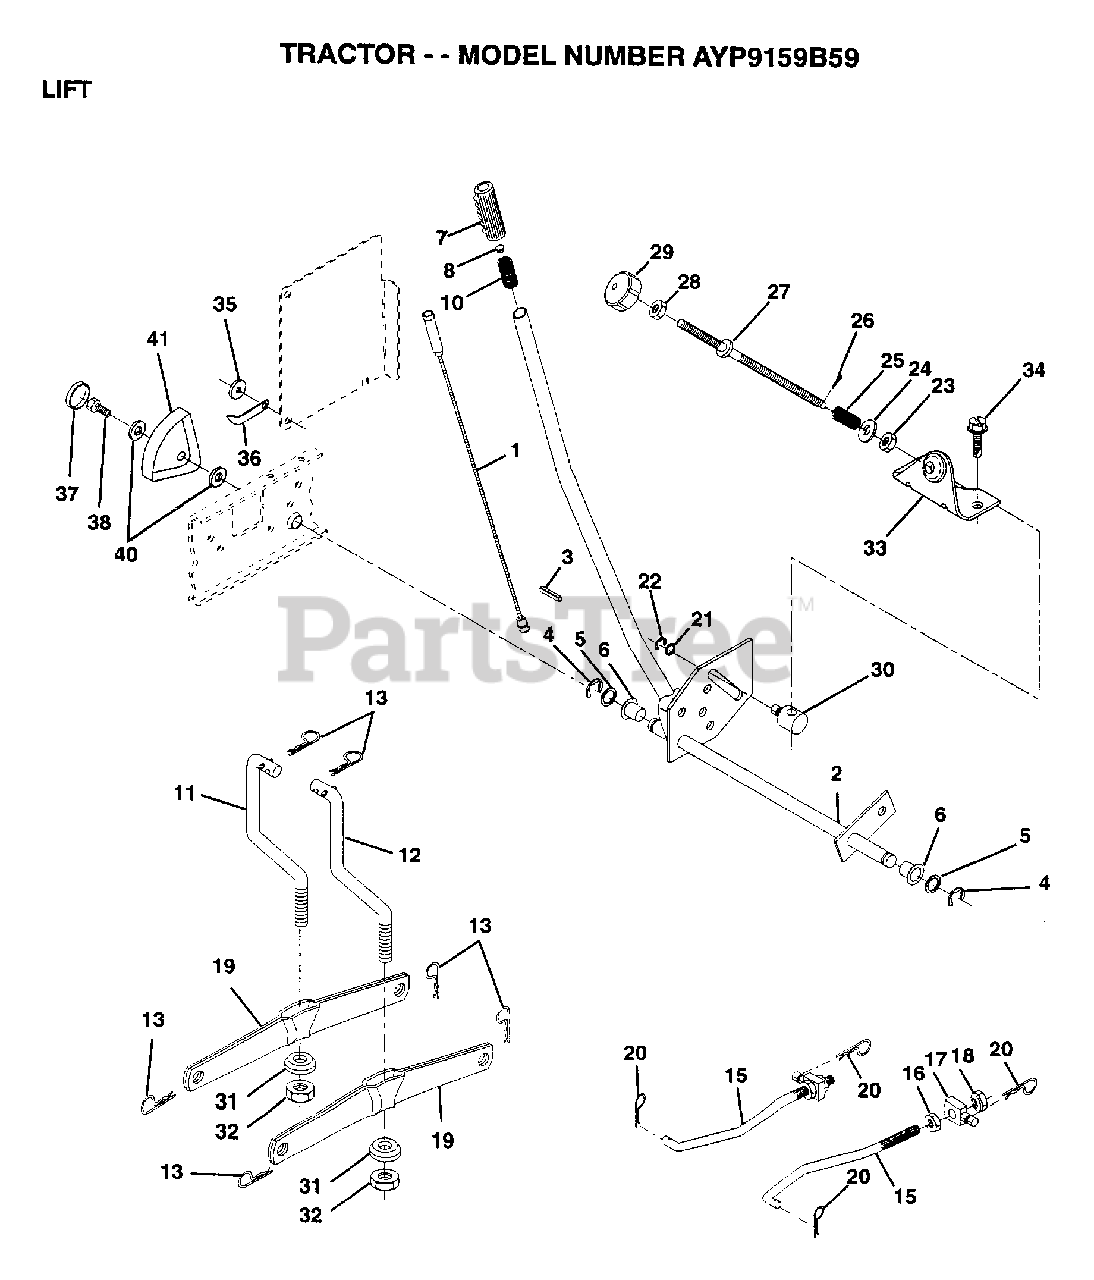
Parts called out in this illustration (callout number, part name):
1	WIRE ASM
2	HANDLE.LIFT.LH.
3	PIN GROOVE
5	WASHER
6	NYLON BEARING
7	GRIP HANDLE
15	LINK.FRONT
16	NUT
17	TRUNION
18	NUT.LK.W/WSH.1/2.
19	ARM SUSP REAR
20	RETAINER.SPRING
21	WASHER
22	KLIP RING
23	NUT T
24	WASHER
25	SPRING T
28	NUT
29	KNOB INF 3/8-16
30	TRUNION LT
31	BEARING PVT LH
32	NUT.CROWNLOCK.3/8
33	BRACKET STOP INF
34	SCREW LT
35	WASHER T
36	POINTER HGT IND
37	"PLUG,HOLE"
38	SCREW
40	WASHER
41	HEIGHT INDICATOR
